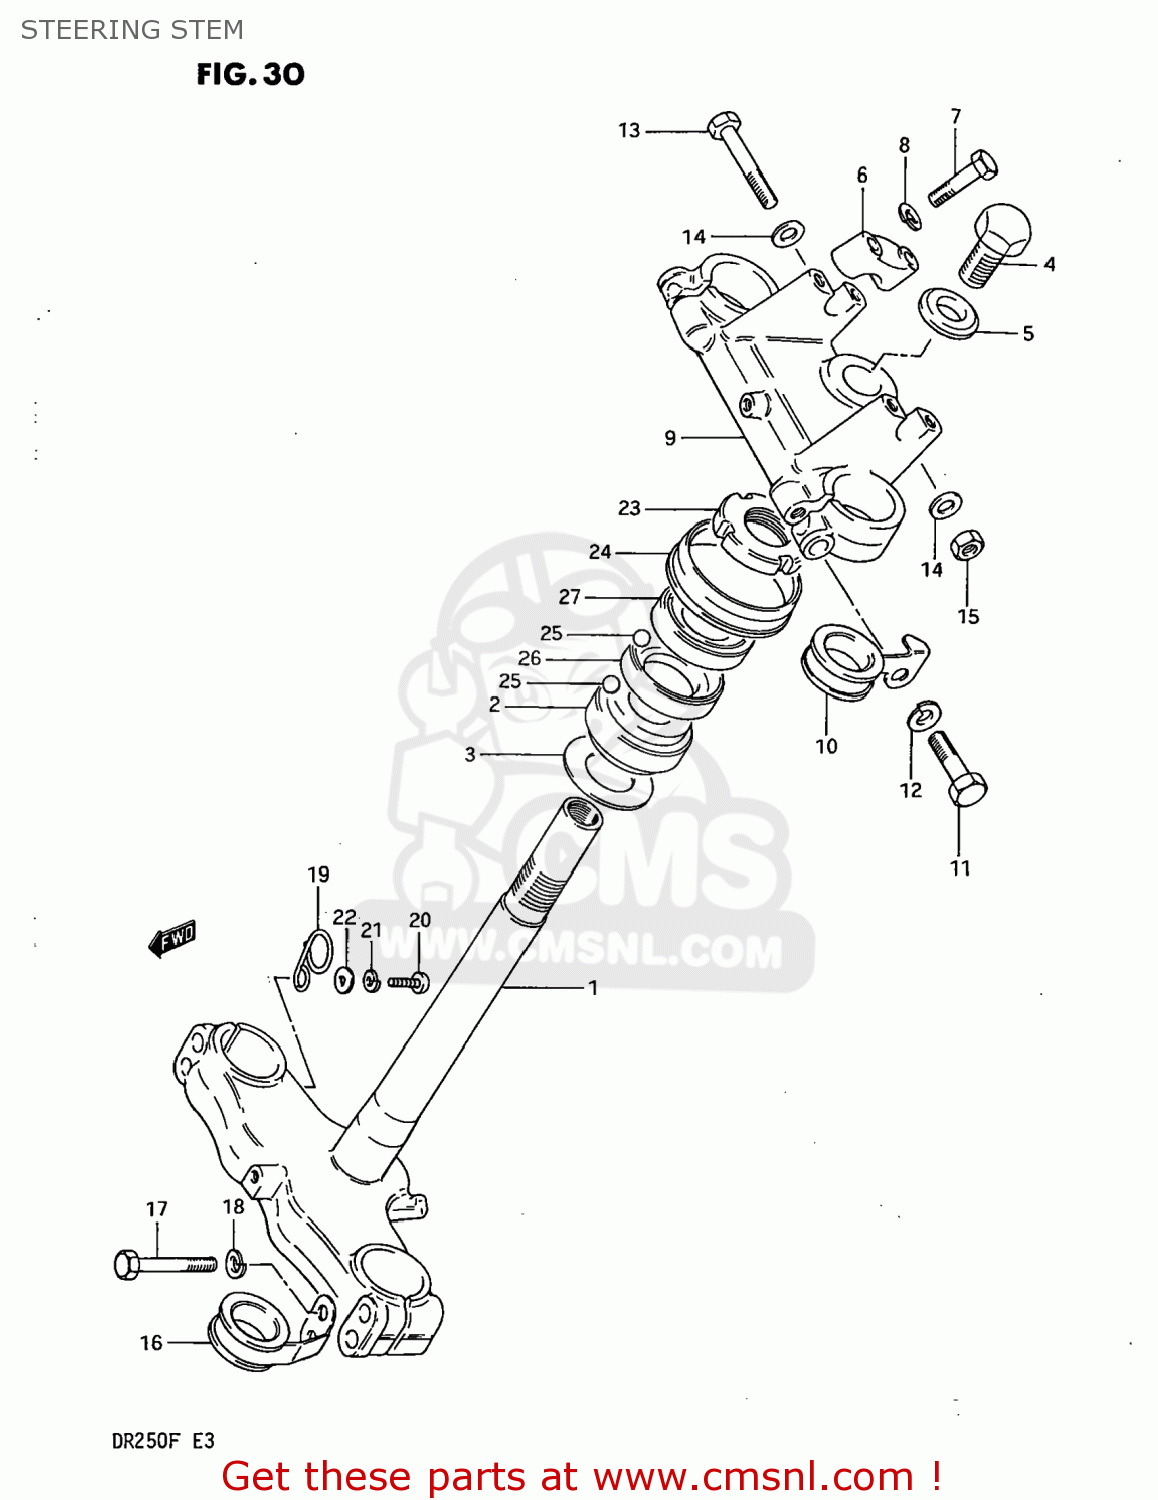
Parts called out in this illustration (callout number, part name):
1	STEM,STEERING
2	BEARING
3	WASHER,THRUST
4	BOLT
5	WASHER
6	HOLDER,HANDLEBAR
7	BOLT
8	WASHER,LOCK,8.
9	HEAD,STEERING STEM
10	GUIDE,CABLE
11	BOLT
12	LOCK WASHER
13	BOLT 8X50
14	WASHER
15	NUT
16	GUIDE,CABLE
17	BOLT 8X45
18	WASHER,LOCK,8.
19	CLIP
20	SCREW
21	WASHER,LOCK
22	WASHER, LOWER
23	NUT,STEERING STEM
24	SEAL,STEERING UPR DUST
25	BALL
26	RACE,STEERING,INNER,UPPER
27	RACE,STEERING,OUTER,UPPER
